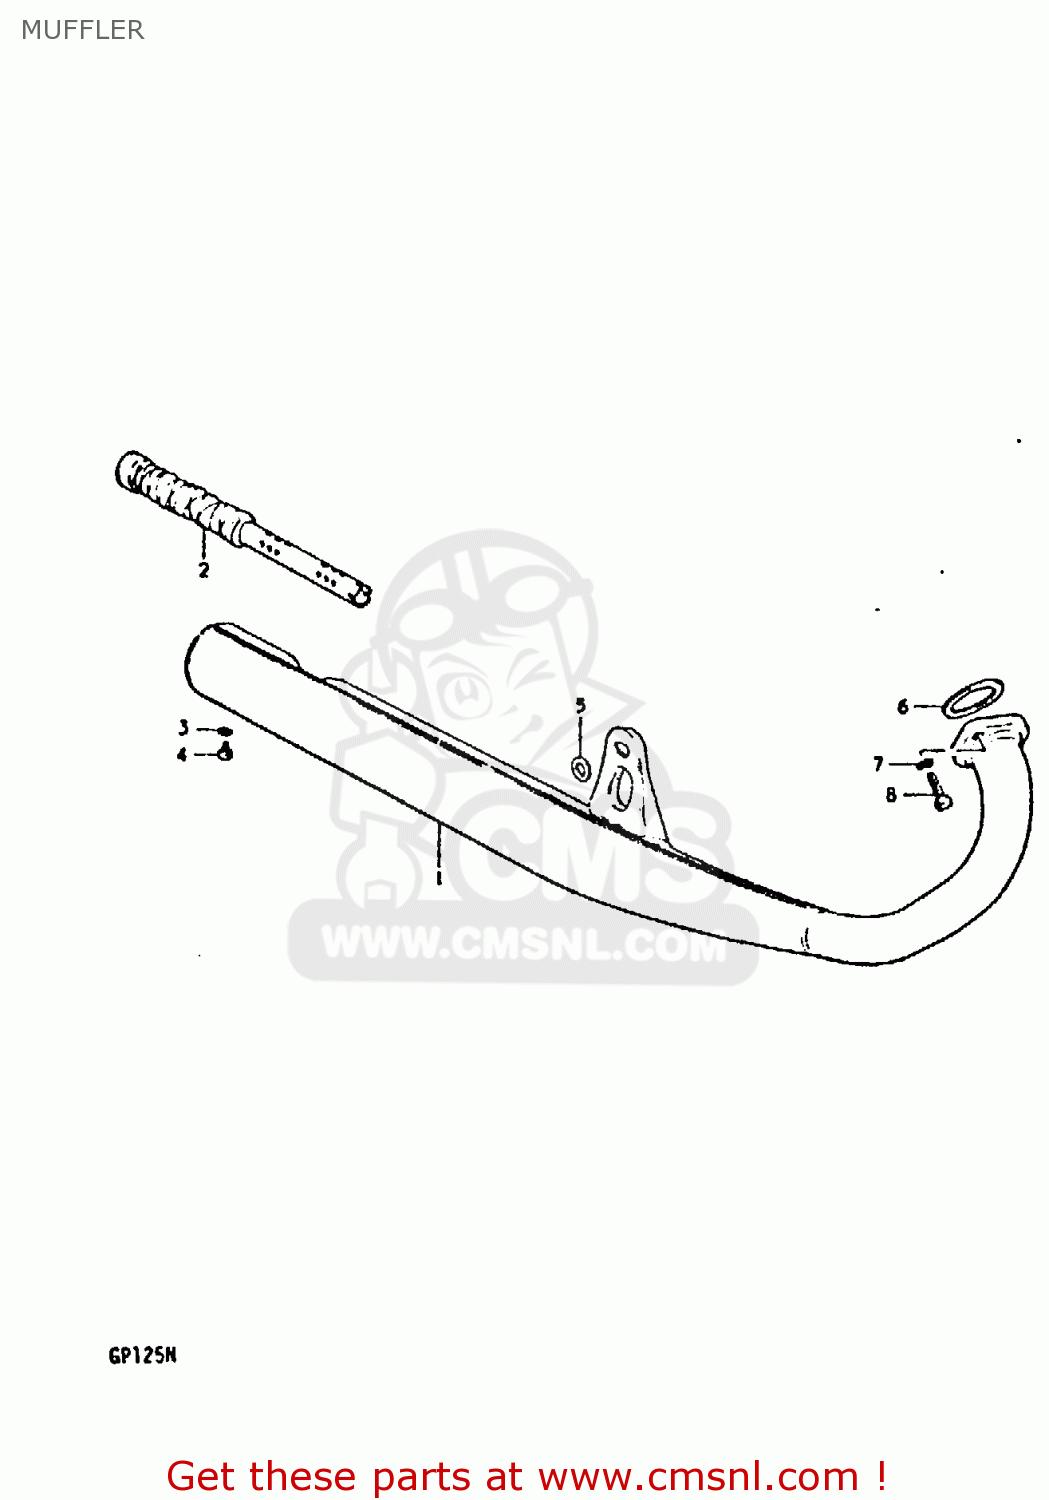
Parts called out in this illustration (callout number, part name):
1	MUFFLER ASSY
2	PIPE, BAFFLE
3	LOCK WASHER
4	BOLT(5X8)
5	WASHER (12.5X24X3.2)
6	GASKET,EXHAUST PIPE (NAS)
7	LOCK WASHER
8	BOLT
